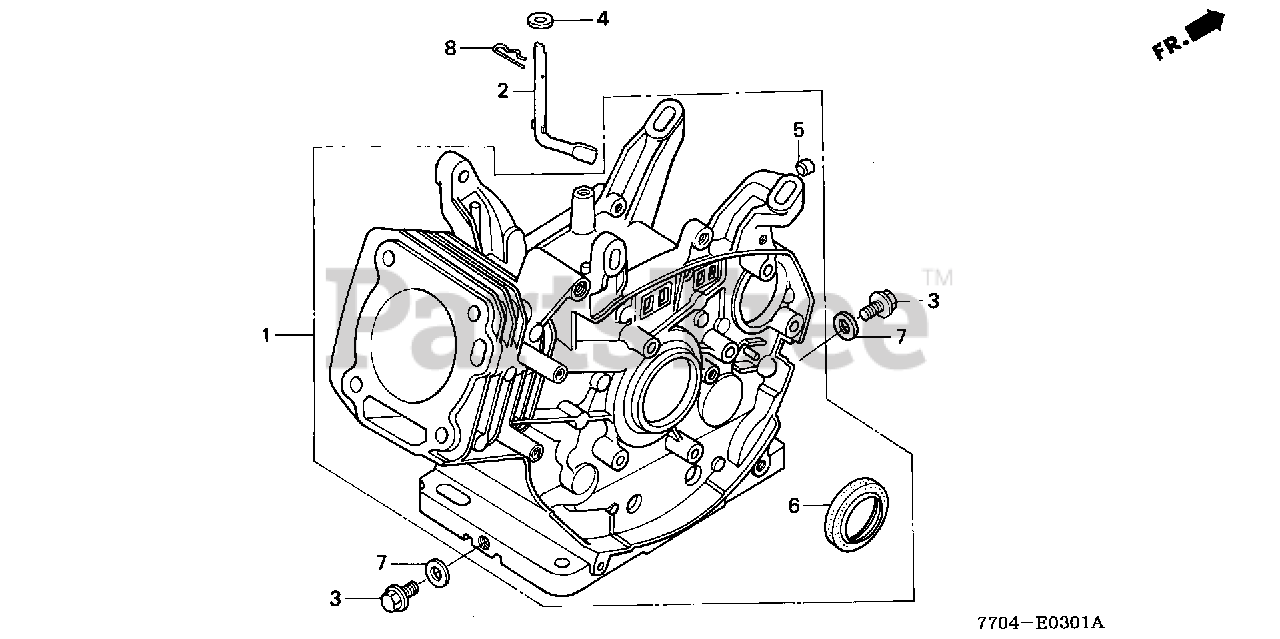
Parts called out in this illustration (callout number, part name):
1	CYLINDER ASSY. (STD)
2	SHAFT, GOVERNOR ARM
3	BOLT, DRAIN PLUG (12X15)
4	WASHER (8.2X17X0.8)
5	PLUG, SEALING (RUBBER 10MM)
6	OIL SEAL (30X46X8)
7	WASHER, DRAIN PLUG (12MM)
8	PIN, LOCK (10MM)
